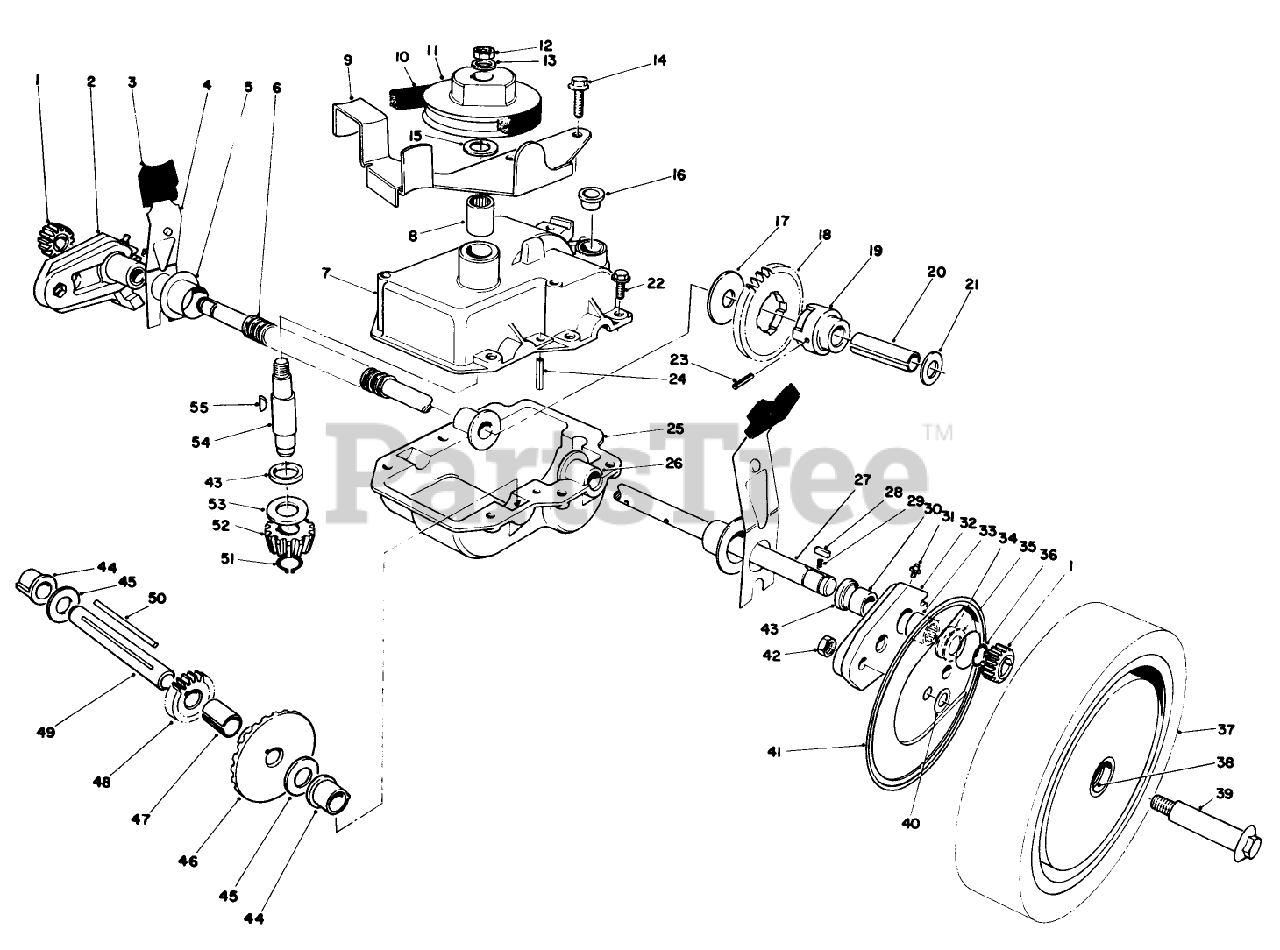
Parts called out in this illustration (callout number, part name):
1	GEAR-PINION
2	PIVOT ARM ASM RH
3	KNOB-ARM
4	SPRING ARM ASM SP
5	CAP-END
6	CONDUIT-CONVOLUTED, SPLIT
7	DISC PRC4
8	BEARING
10	V-BELT
11	PULLEY
12	NUT-HEX
13	WASHER-FLAT
14	SCREW
15	WASHER-THRUST
17	WASHER
18	GEAR-42T
19	DRIVE ADAPTER
21	WASHER-PLAIN
22	SCREW-HWHTF
24	ROLL PIN 3/16 X 1 IN
28	KEY RECTANGULAR
29	SPRING-COMPRESSION
30	BUSHING
31	FITTING-GREASE
35	WASHER-THRUST, OUTER
36	RING-RETAINING
37	WHL/GEAR/TIRE PKG
38	BUSHING
39	WHEEL BOLT
40	WASHER
42	NUT-LOCK
44	BUSHING
45	WASHER-THRUST
48	GEAR-14T
51	RING-RETAINING
52	PINION-BEVEL
53	WASHER-THRUST
55	KEY-WOODRUFF
